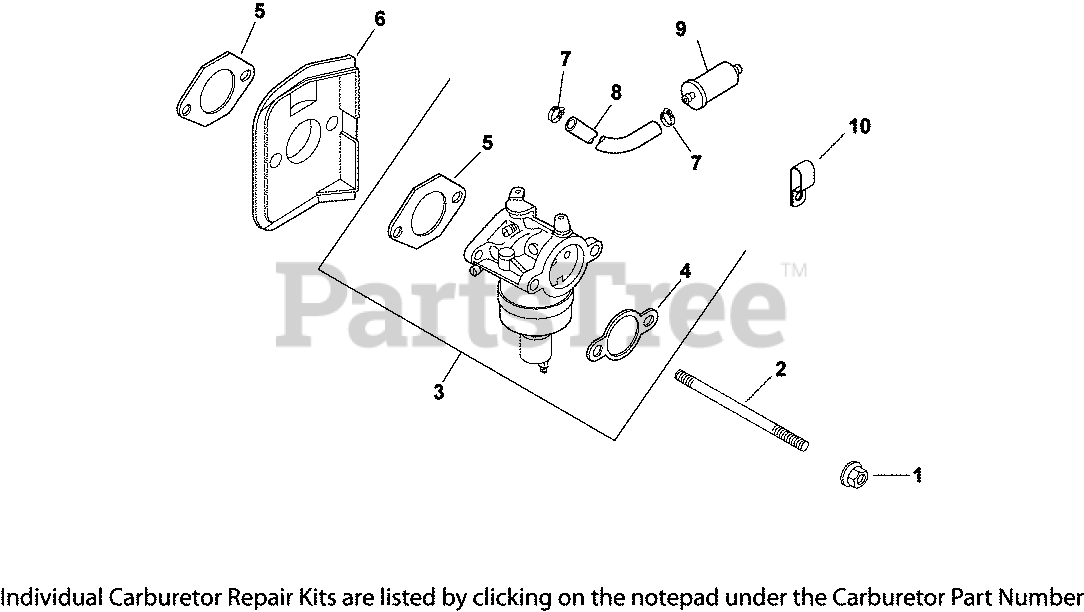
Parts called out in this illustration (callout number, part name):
1	NUT, FLG M6X1.0
2	STUD,M6X1.0X116
3	KIT, CARBURETOR w/GASKETS
4	GASKET, AIR CLEANER BASE
5	GASKET, CARBURETOR
6	DEFLECTOR, HEAT
7	CLAMP, HOSE (KM)-USE 25 237 31-S
9	FILTR,FUEL 75 MICRON (GRAVTY FEED)
10	CLIP, CABLE
